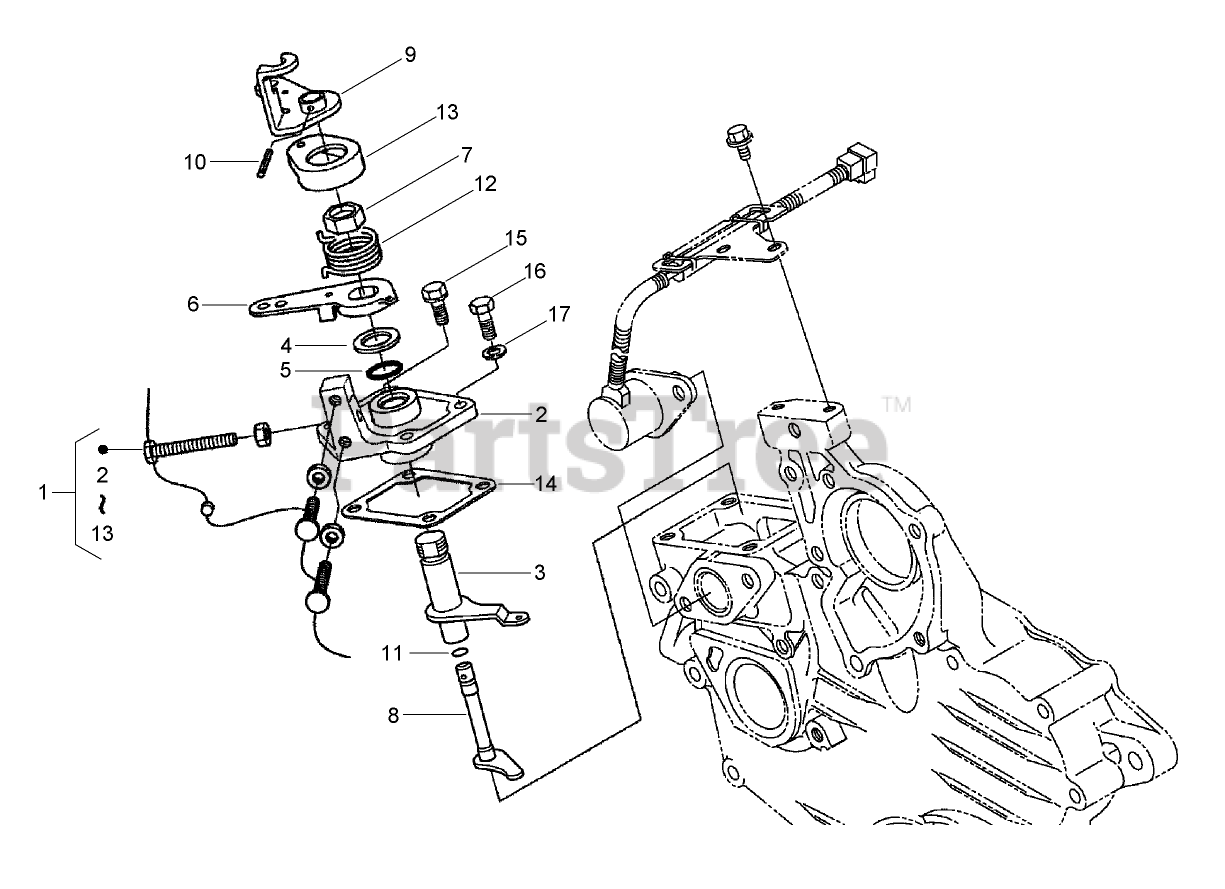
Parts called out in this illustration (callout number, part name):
1	SPEED CONTROL PLATE ASM
2	PLATE-CONTROL, SPEED
3	LEVER-GOVERNOR
4	COLLAR
5	O-RING
6	LEVER-CONTROL, SPEED
7	NUT-CONTROL, SPEED
8	SHAFT-LEVER
9	LEVER-STOP, ENGINE
10	PIN-SPRING
11	O-RING
12	SPRING-RETURN
14	GASKET-PLATE, CONTROL
17	GASKET
